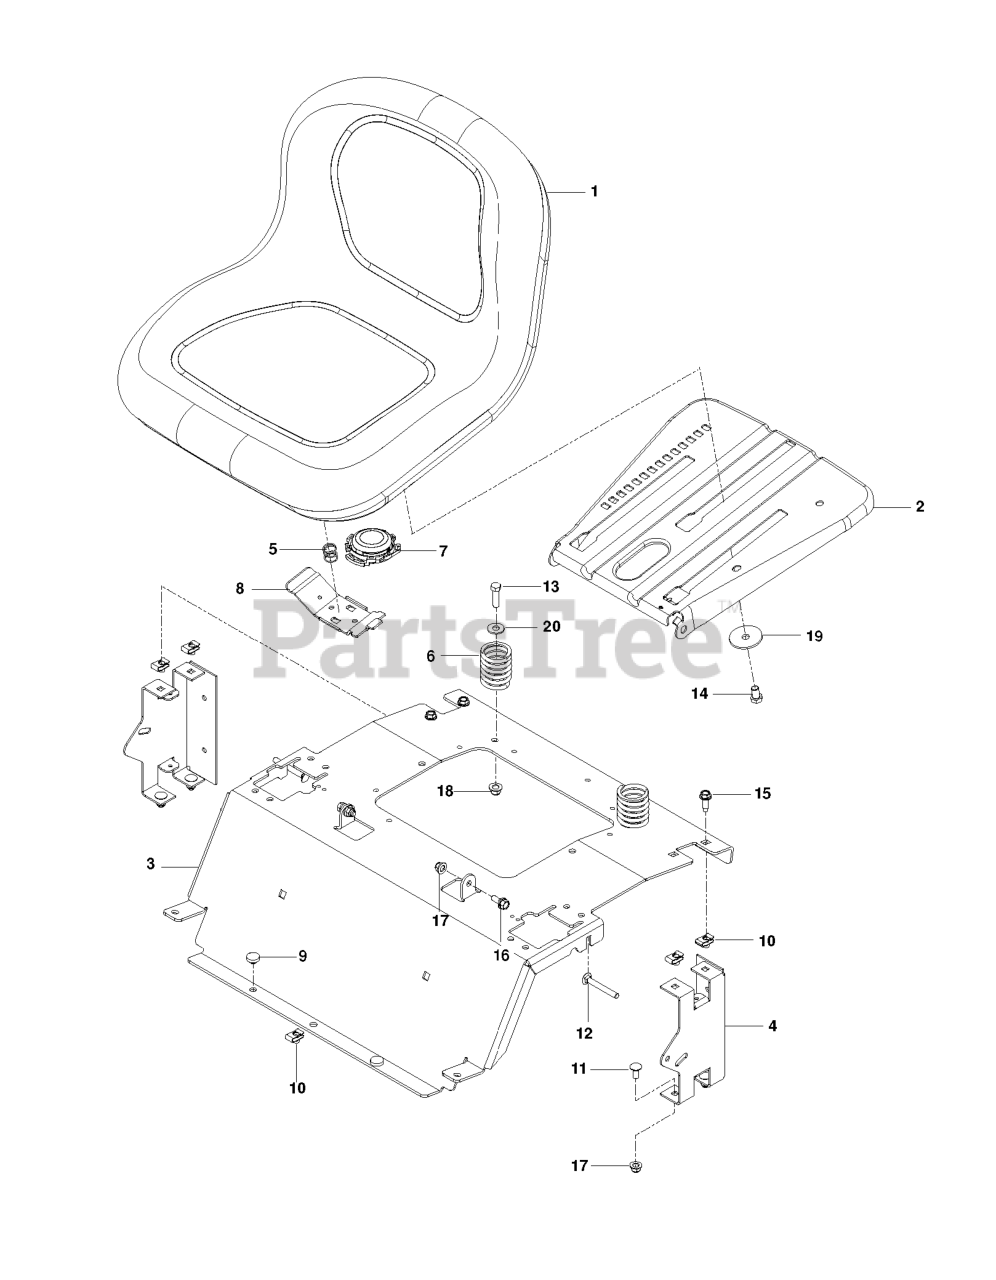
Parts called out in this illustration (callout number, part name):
1	SEAT.TH150.MS498.GRY.HUSQ.TEX
2	PAN.ASM.SEAT.3PT
3	SUPPORT SEAT ORANGE
4	SUPPORT REAR SEAT BLACK
5	SPRING.LATCH.SEAT.TEX
6	SPRING, SEAT
7	SWITCH, SEAT N/C
8	HANDLE.SLIDE.SEAT.TEX.BLACK
9	GROMMET, BUMPER
10	U-CLIP 5/16-18 NUT RETAINER
11	RP BOLT 5/16-18 X3/4 ZN/YEL GR
12	RHSNB 5/16-18 X 2-1/2 GR5 ZD
13	BOLT
14	HCS 3/8-16 X 5/8 GR 5 ZD
15	SCREW.THDROL.5/16-18X3/4.TTY
16	BOLT, SHOULDER
17	5/16-18 NYLOC FLANGE NUT
18	NUT 3/8-16 HEX FLG NYLOC ZD
19	WASHER, 3/8 SPEC
20	RP WASHER 3/8 FLAT
